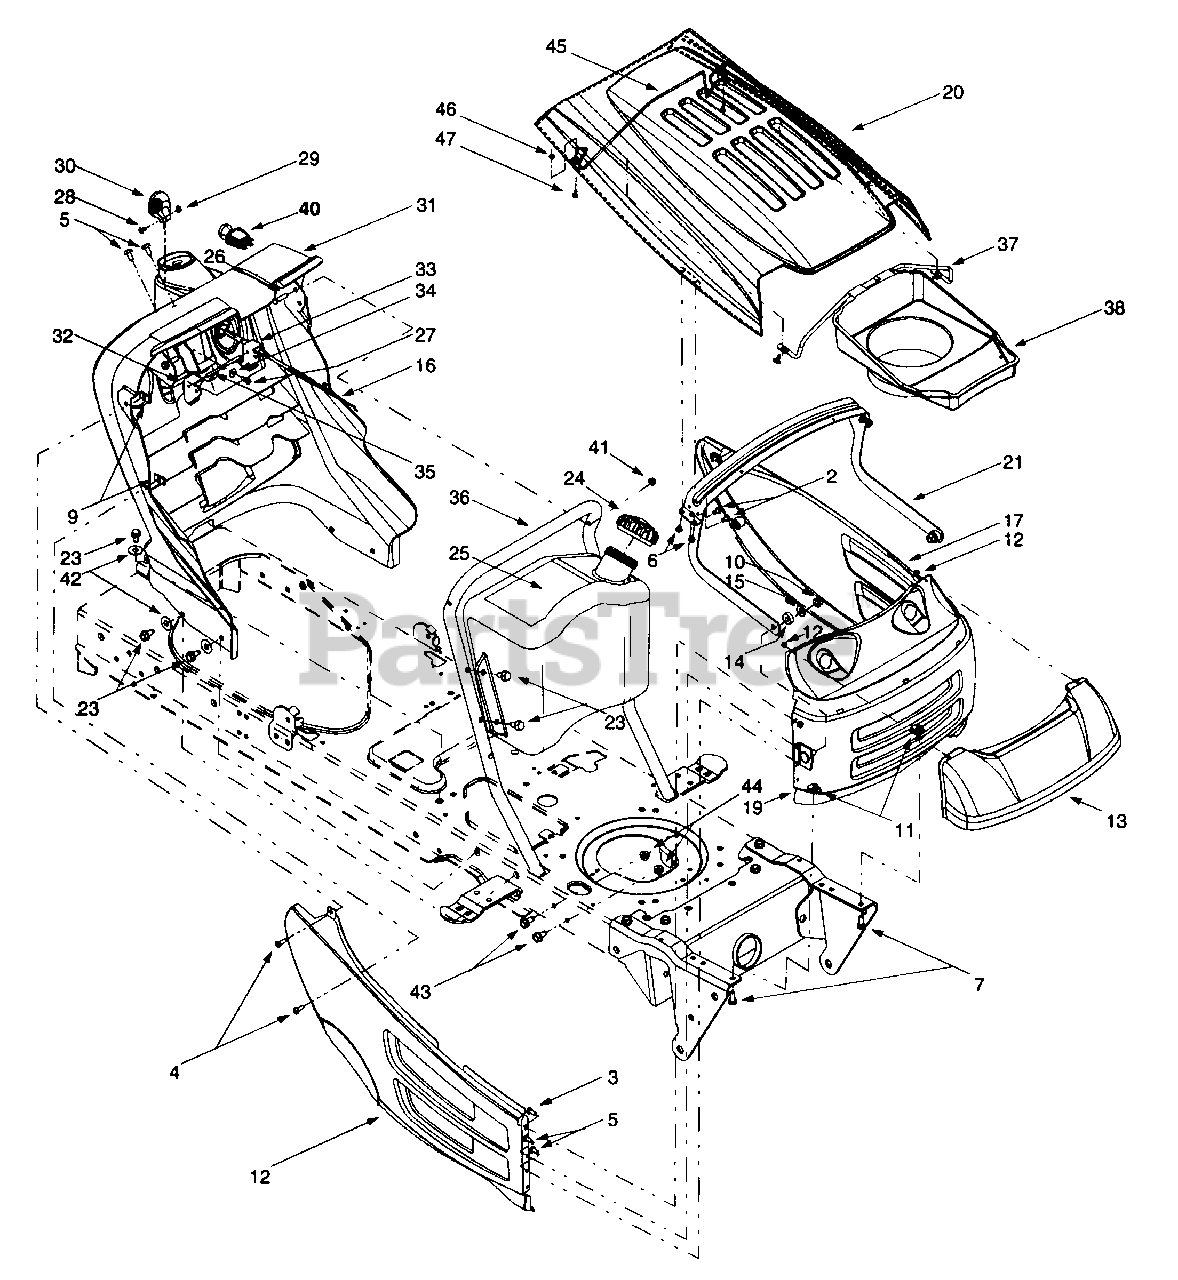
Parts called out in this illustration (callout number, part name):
2	Self-tapping Screw, 1/4-20 x .5
3	Hex Cap Screw, 1/4-20 x .62
4	Phillips Pan Screw, 1/4-20 x .75
5	Truss Phillips Screw, 1/4-20 x .625
6	Screw, #10-16 x .375
7	Hex Cap Screw, 5/16-18 x .75
9	U-type Speed Nut, 1/4-20
10	Flange Lock Nut, 3/8-16
11	U-nut, 5/16-18
12	Retainer Nut, 3/8
13	Headlight Lens (8-style)
14	Rubber Washer, .87 x .33
15	Bell Washer, .401 x .87 x .063
16	Choke Knob/Cable
24	Fuel Cap
25	Fuel Tank
26	Self-tapping Screw, 1/4-20 x 1.25
27	Self-tapping Screw, 1/4-15 x .75
28	Truss Phillips Screw, #8-32 x .375
29	Hex Nut, #8-32
30	Throttle Control Knob
31	Dash Panel (8-style)
32	Cruise Control Button
33	Parking Brake Button
34	Flat Washer, 9/32 x 1/2 x 1/16
35	Brake/Cruise Pivot Rod
38	Heat Shield (8-style)
40	Electric PTO Switch
41	Hex Flange Lock Nut, 1/4-20
42	Flat Washer, .349 x 1.0 x .063
43	Screw, 5/16-18 x .875 (Grade 5)
44	Hex Nut, 5/16-18
45	Hood Latch (8-style)
46	Hex Nut, #10-32
47	Machine Screw, #10-24
